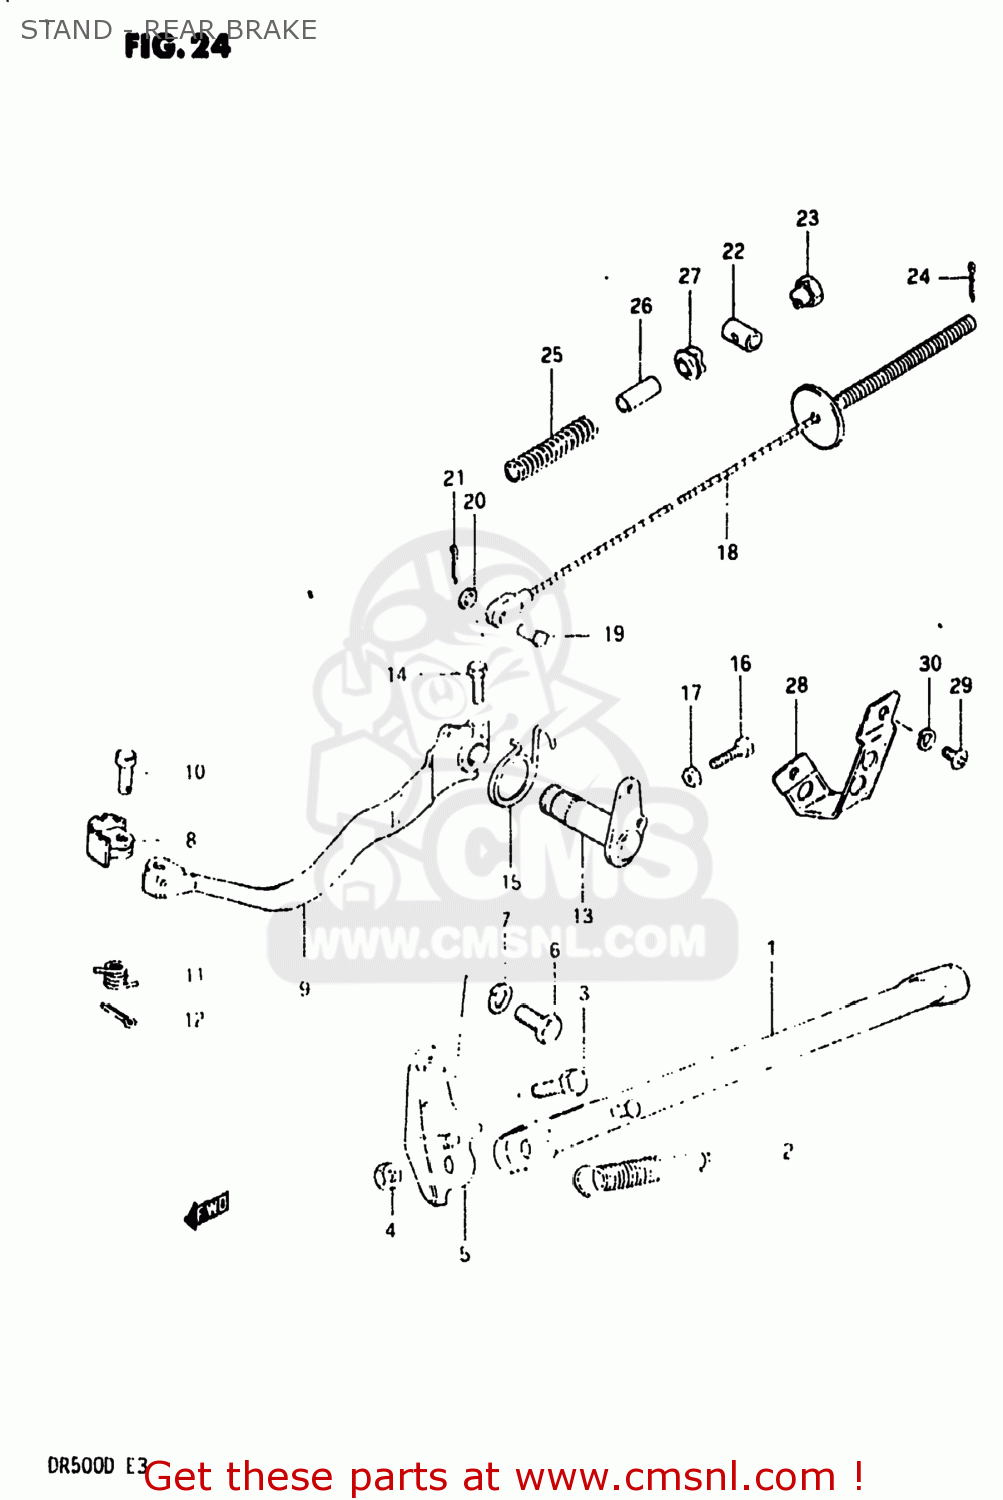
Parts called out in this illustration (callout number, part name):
1	STAND,SIDE
2	SPRING
3	BOLT(10X30)
4	NUT
5	BRACKET,PROP STAND
6	BOLT(10X19)
7	LOCK WASHER
8	PEDAL,BRAKE
9	ARM,BRAKE PEDAL
10	PIN
11	SPRING
12	PIN
13	ARM,BRAKE PEDAL
14	BOLT
15	SPRING
16	BOLT(6X23)
17	NUT
18	CABLE,RR BRAKE
19	PIN(L:17.5)
20	WASHER
21	PIN
22	PIN,BRAKE CABLE ADJUSTER
23	NUT (6MM)
24	PIN
25	SPRING
26	CUSHION,FR GRILLE,UPPER
27	CUSHION
28	GUIDE,CABLE
29	SCREW
30	LOCK WASHER
